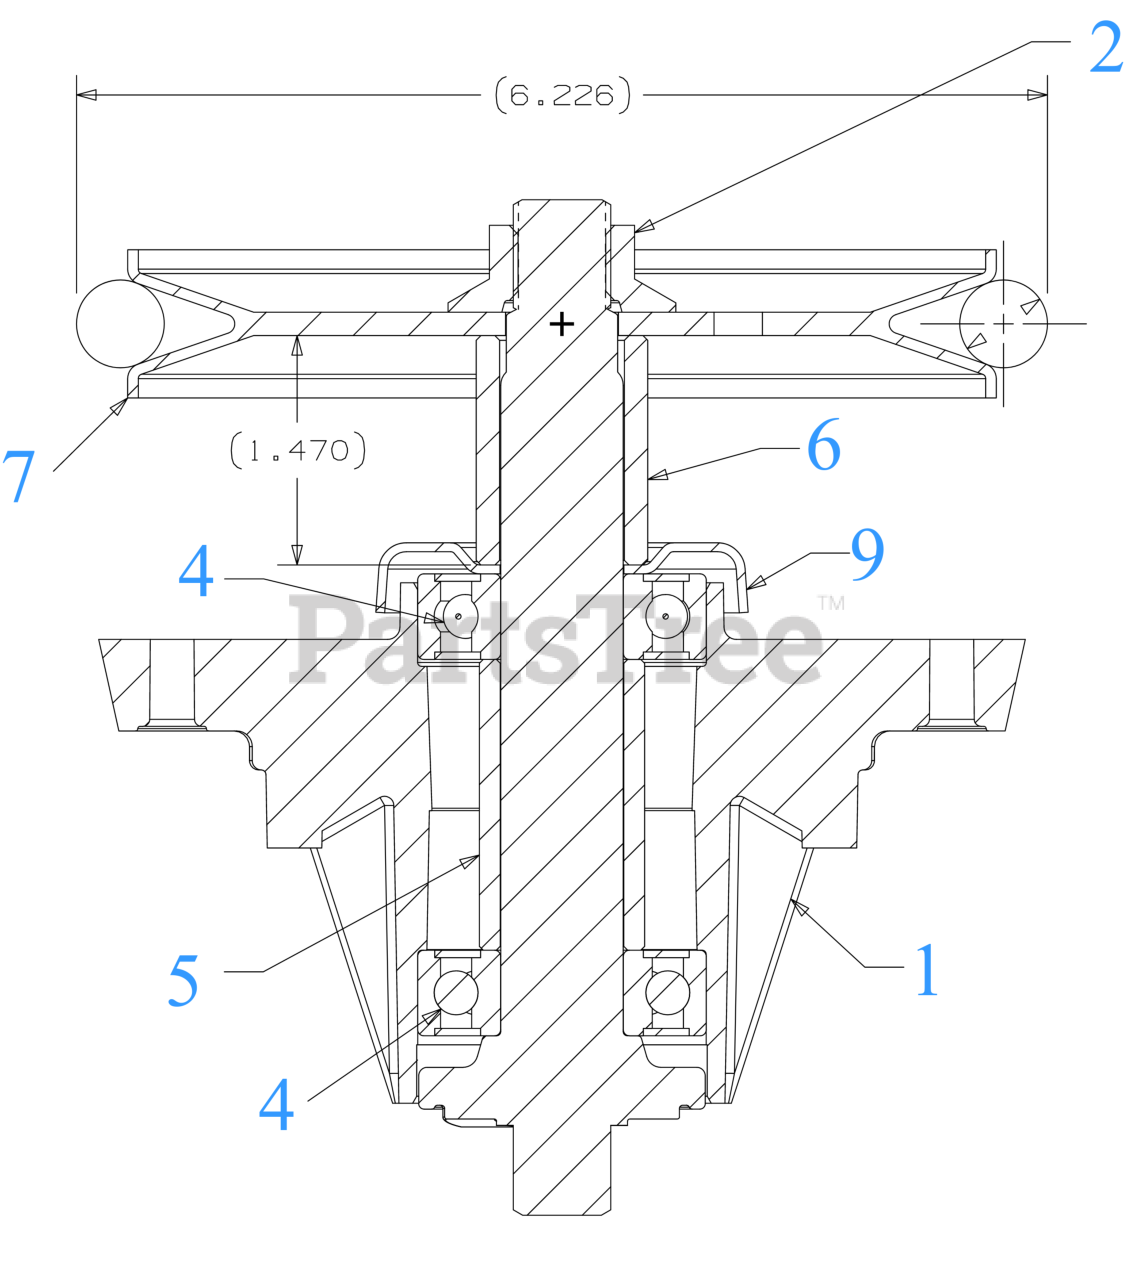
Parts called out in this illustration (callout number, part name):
1	DECK SPINDLE HOUSING
2	FLANGE NUT 5/8-18
4	BALL BEARING
5	SPACER- .792 x 1.060 x 1.860
6	SPACER .800 x 1.100 x 1.470 LG
7	DECK PULLEY 5.4" DIA
9	SHIELD-BRG DECK
